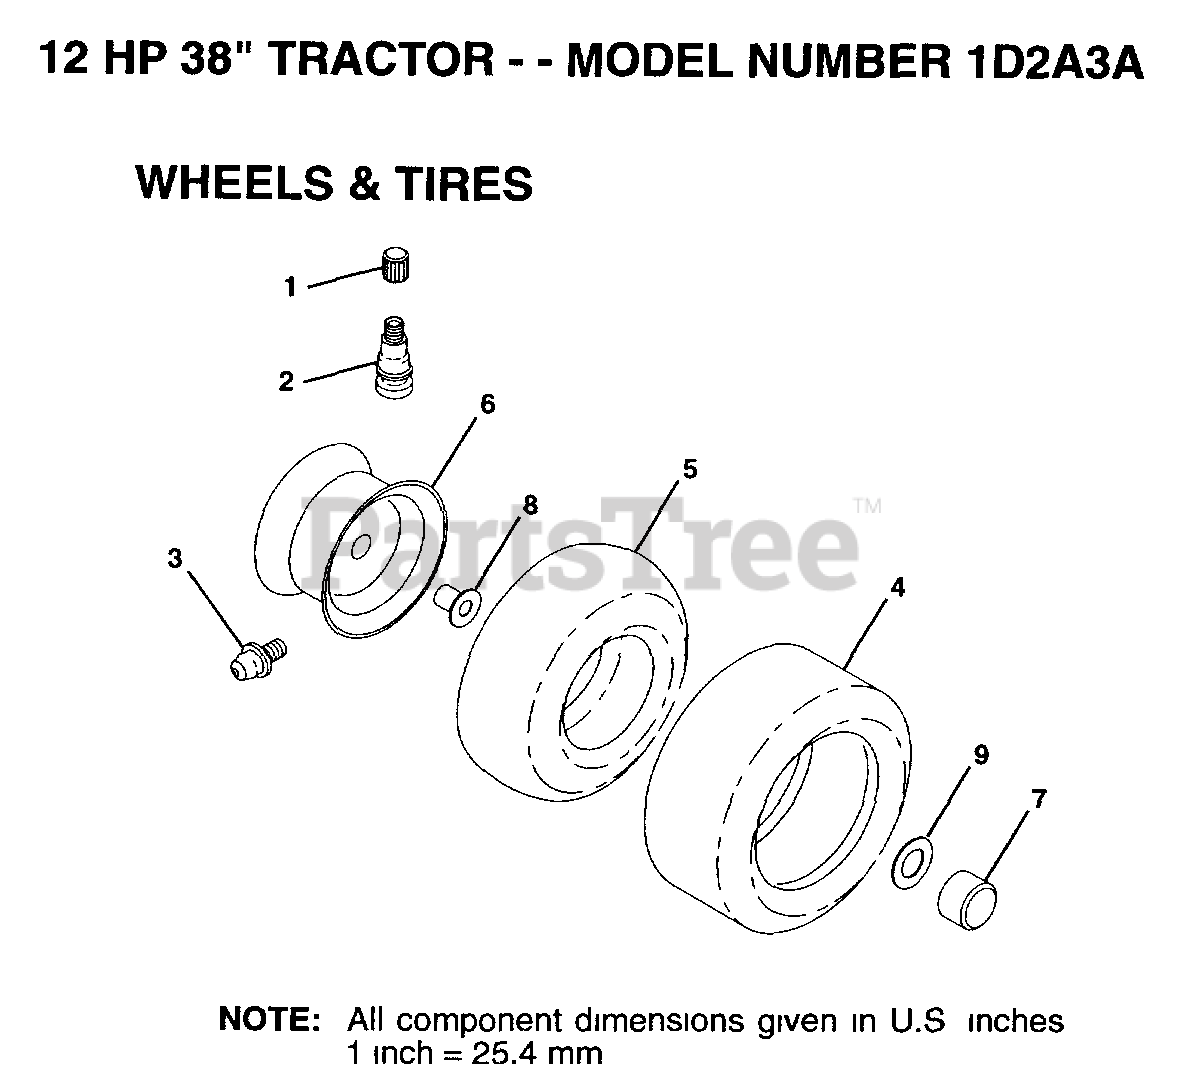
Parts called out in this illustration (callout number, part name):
1	VALVE CAP
2	VALVE STEM LT
3	FITTING LT
5	TUBE.5.3/4.5/6
7	HUB CAP
8	"FLANGE, BEARING"
9	WASHER
